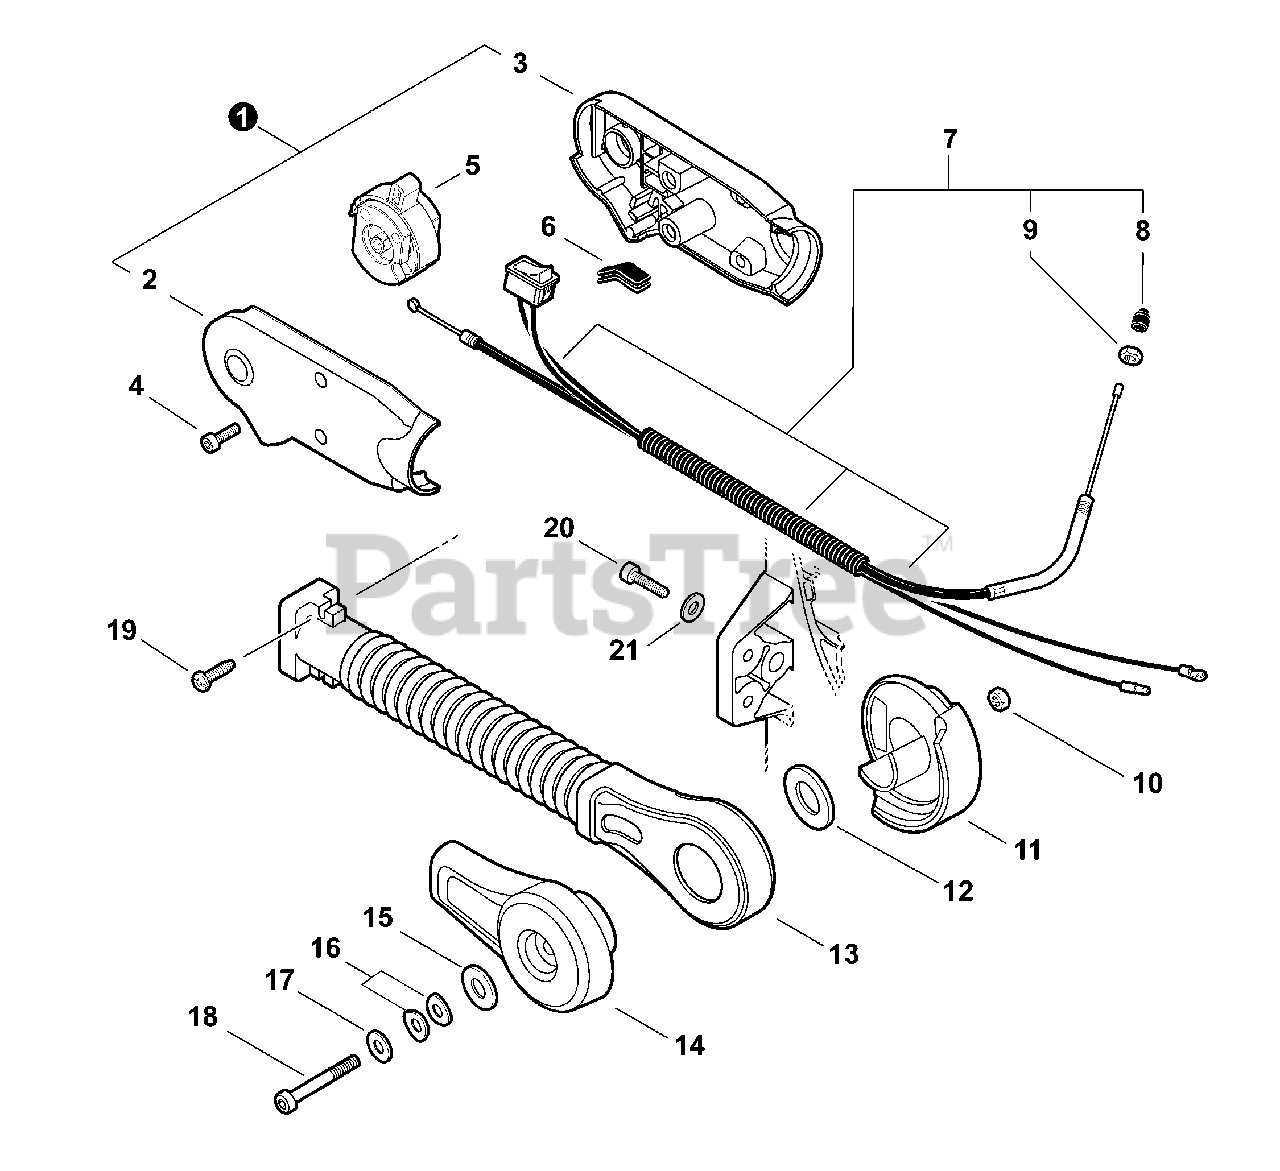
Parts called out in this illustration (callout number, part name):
1	CONTROL HANDLE SET
2	GRIP, LEFT THROTTLE
3	GRIP, RIGHT THROTTLE
4	BOLT, TORX 5×16
5	THROTTLE CONTROL ASSY
6	GROMMET
7	CABLE ASSY, CONTROL
8	CAP, DUST
9	NUT, HEX M6
10	NUT, LOCK M6
11	BRACKET, ARM - INNER
12	WASHER 45
13	ARM, THROTTLE CONTROL
14	BRACKET, ARM - OUTER
15	WASHER 6.5×15.5×0.6
16	WASHER, FRICTION 6.6×14.3
17	WASHER 6.6×20×1.6
18	BOLT, TORX 6×75
20	BOLT, TORX 5×20
21	WASHER 5.5×16×2T
